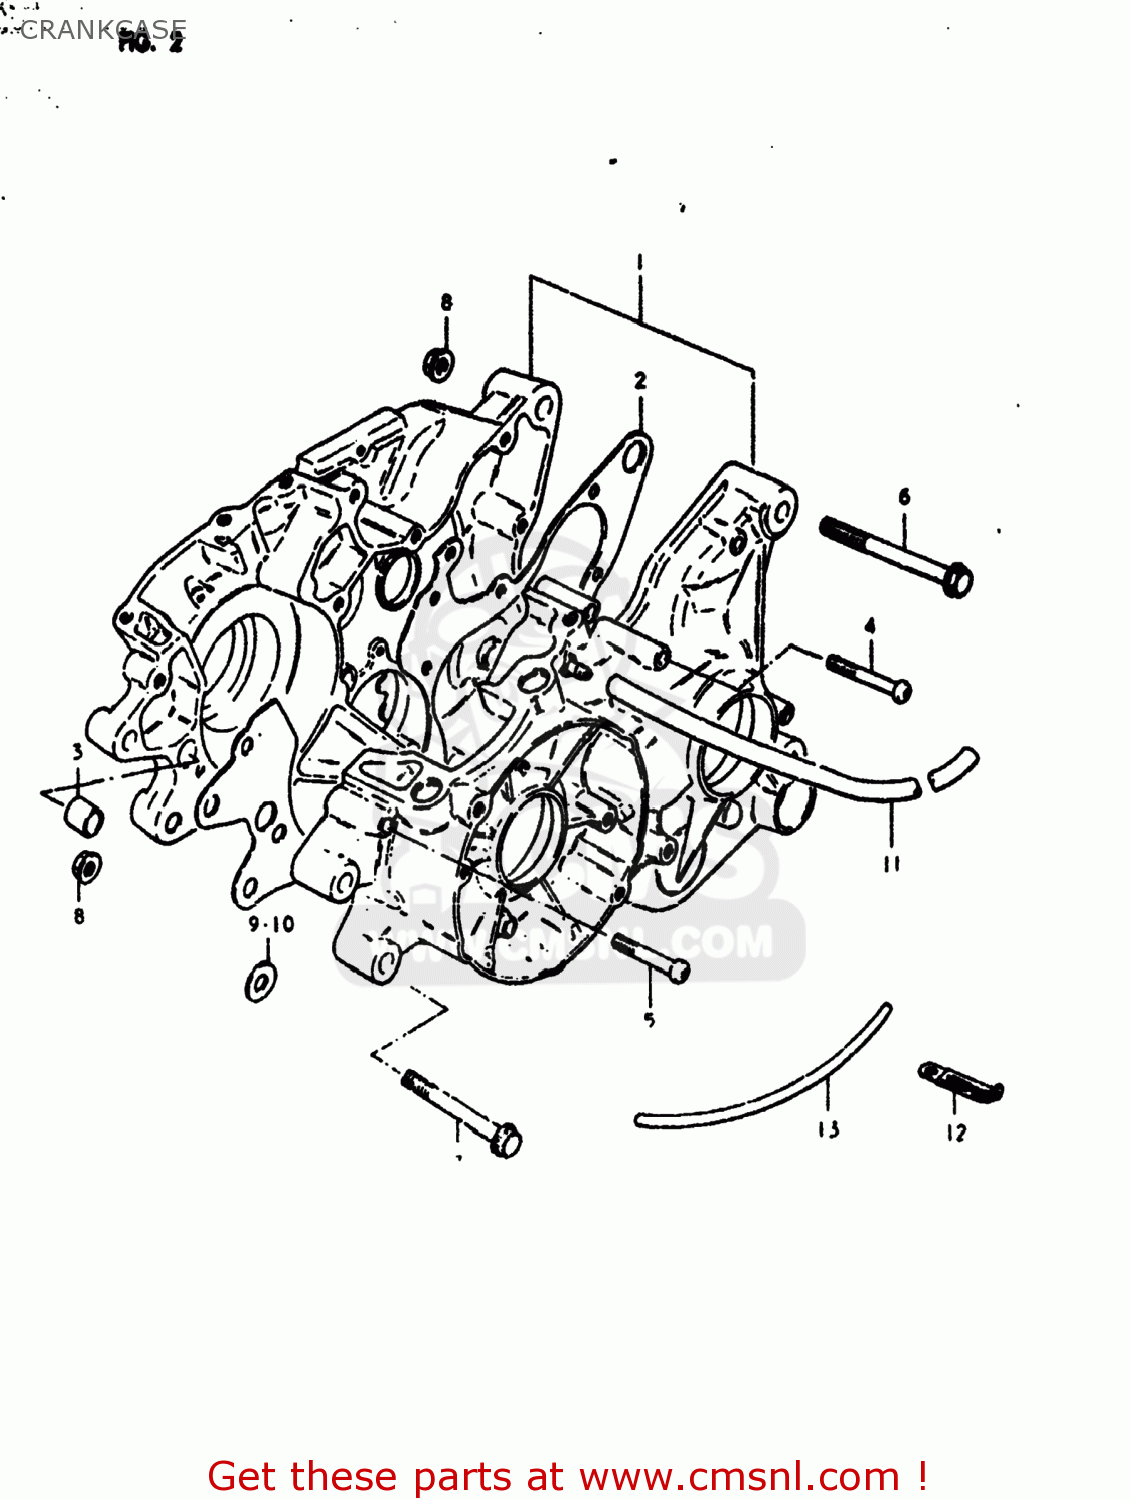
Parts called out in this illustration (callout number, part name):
1	CRANKCASE SET
2	GASKET,CRANKCASE (MCA)
3	PIN
4	SCREW
5	SCREW (6X45)
6	BOLT 8X90
7	BOLT(8X67)
8	NUT
9	WASHER
10	WASHER
11	HOSE
12	CLAMP
13	HOSE
